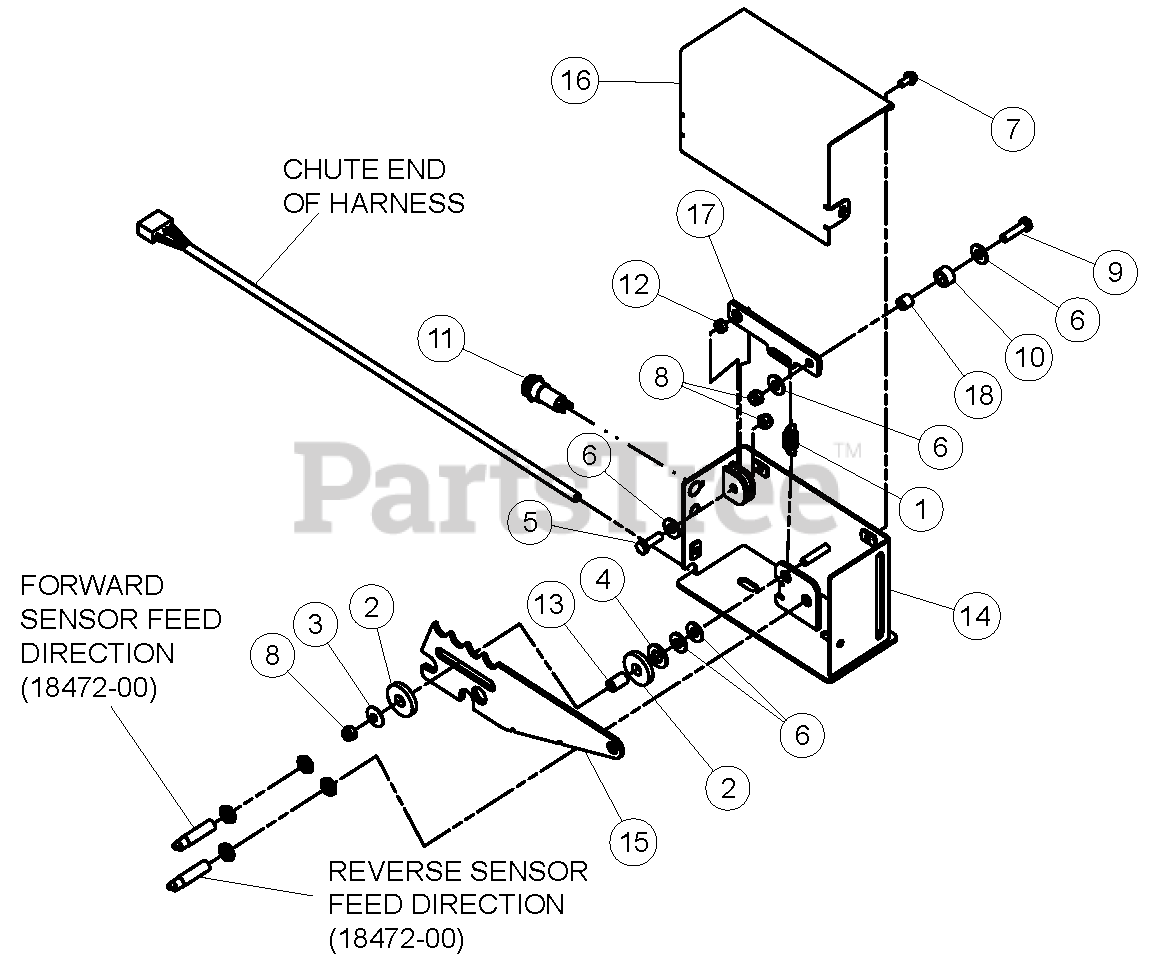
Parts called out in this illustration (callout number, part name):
1	SPRING, CONTROL BAR
2	WASHER, UHMW SPACER
3	WASHER, 5/16 SPRING
4	WASHER, 1/2 SAE FLAT
5	BOLT, 5/16 X 1 HEX HD
6	WASHER, 5/16 FLAT
7	BOLT, SERR. FLANGE 1/4 X 1/2
8	NUT, 5/16 NYLOCK
9	BOLT, 5/16 X 1-1/4 HEX
10	NYLON ROLLER, .75 OD X .502 ID X .440
11	LED, TRI-COLOR 12V 3-TERM BASE
12	SPACER, IDLER PIVOT
13	SPACER, .50 X .785
15	BAR, SWITCH CONTROL
16	COVER, CONTROL BOX
17	LINK, DETENT
18	SPACER, .50 OD X .35 ID X .47
